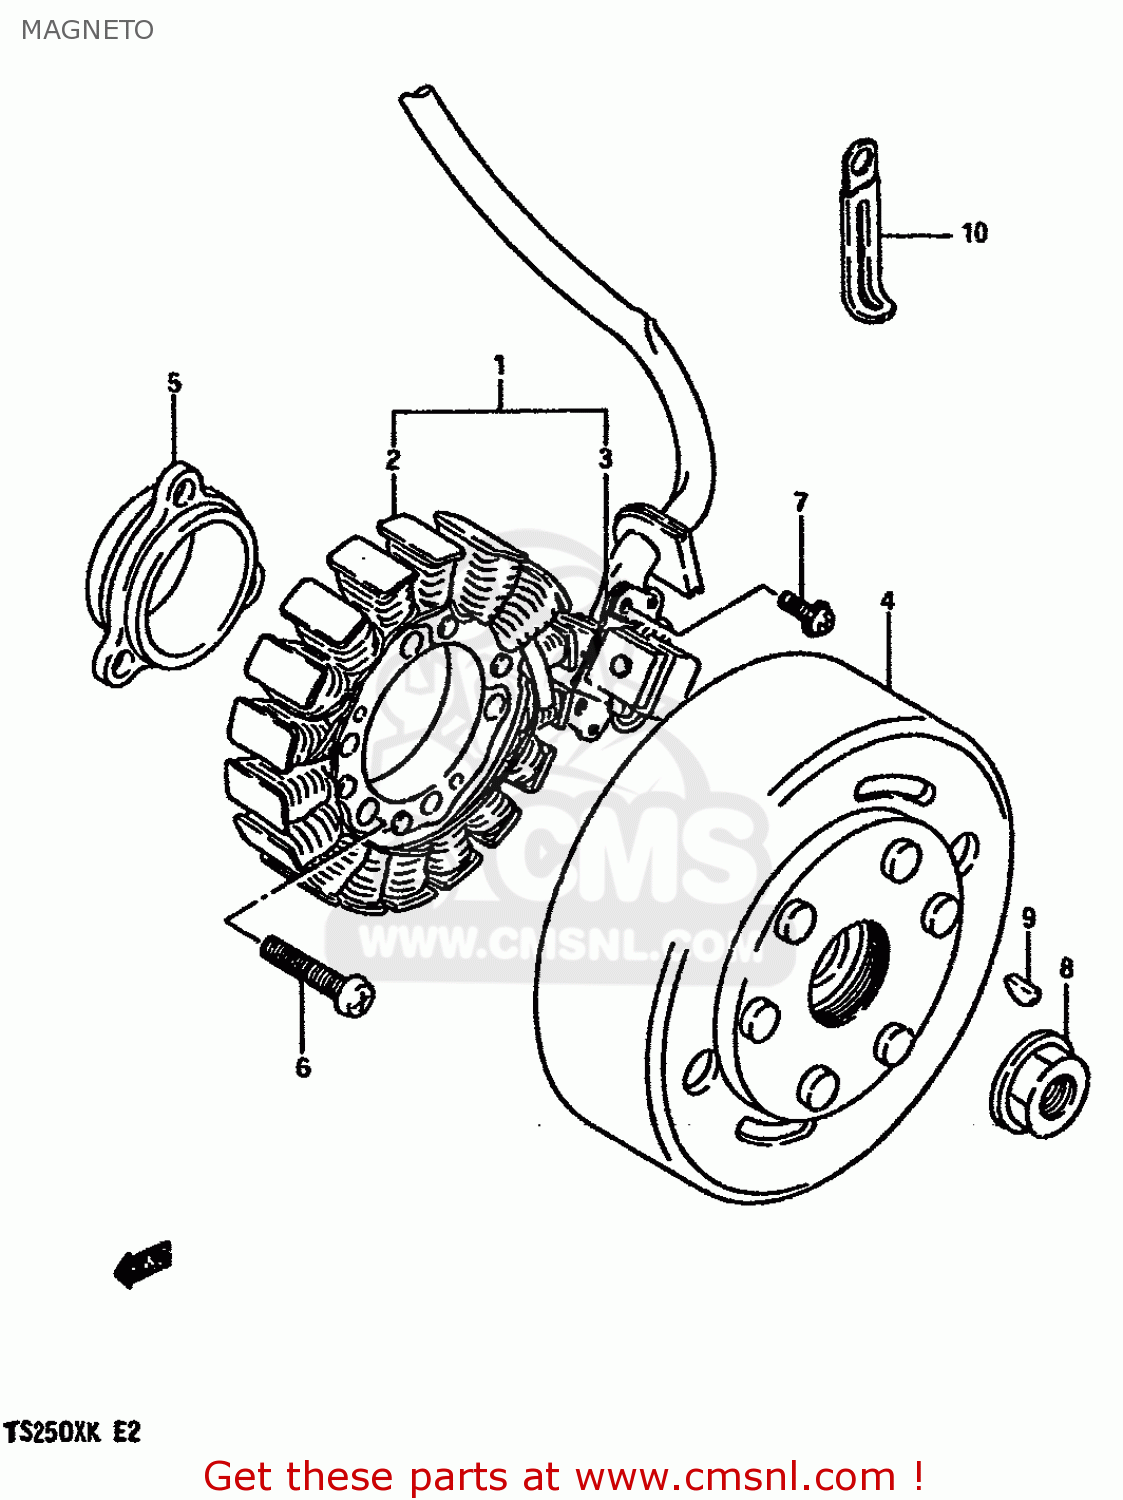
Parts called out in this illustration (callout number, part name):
1	STATOR ASSY
2	ARMATURE ASSY
3	SENSOR,TIMING
4	ROTOR
5	SPACER
6	SCREW,6X30
7	SCREW
8	NUT
9	KEY 4MM
10	CLAMP
